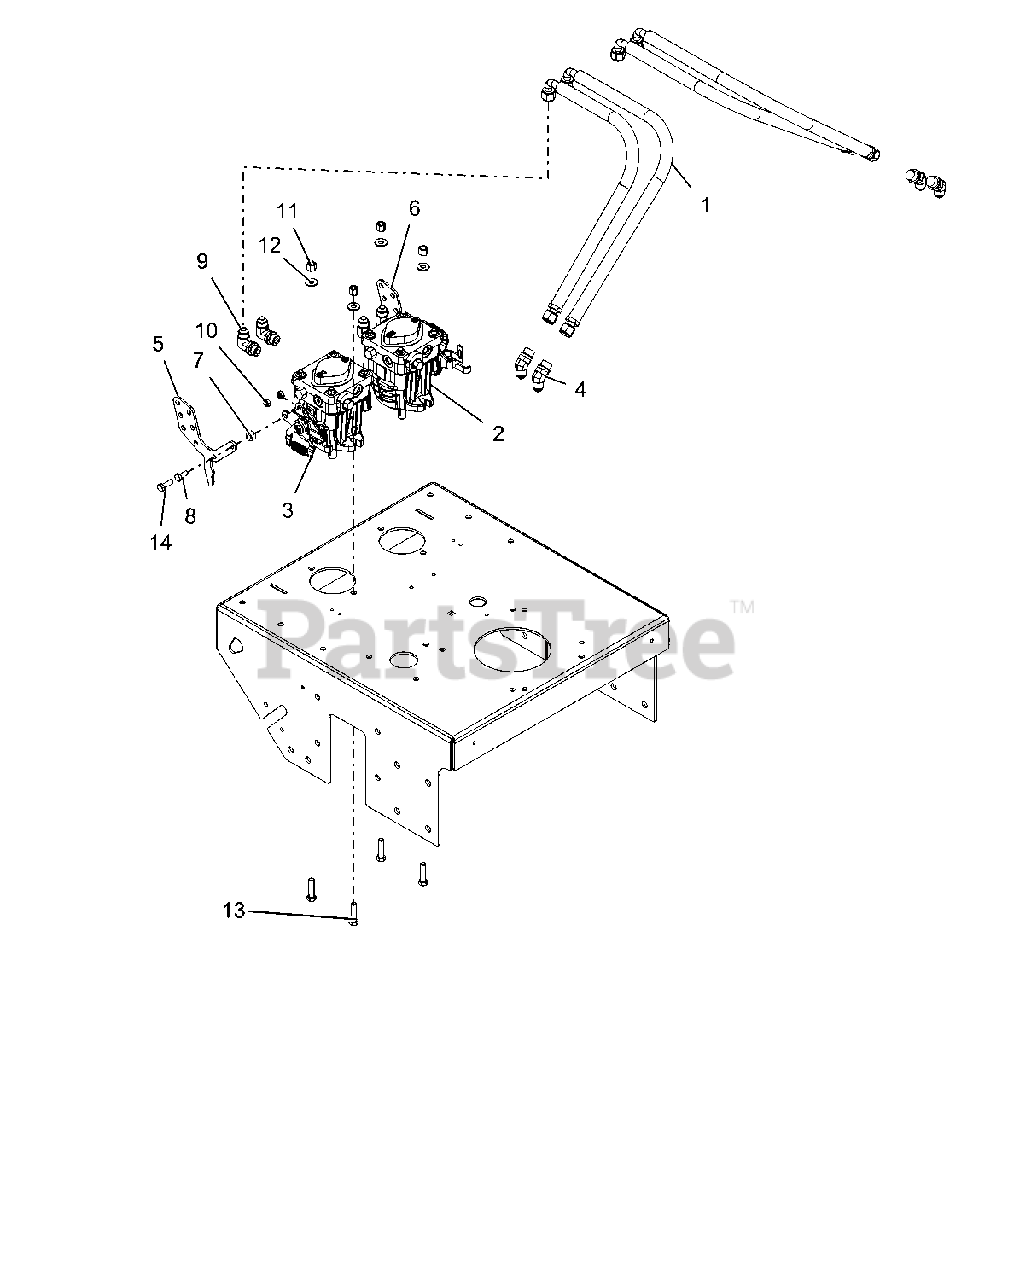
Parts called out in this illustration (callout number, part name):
1	HOSE, HYD 1/2 X 26 1/2 EZFLEX
2	PUMP, LH HYD PE (10CC)
3	PUMP, RH HYD PE (10CC)
4	45 DEGREE HIGH PRESSURE FITTING
5	BRKT, RH PUMP CONTROL WRS
6	BRKT, LH PUMP CONTROL WRS
7	BSHG, SLV REV
8	BLT-HEX .31-18X.75 GR5 YWZC
9	FTG, ADP JIC-ORB 6801-08-08
10	NUT-LK-CTR-JAM .31-18 YWZC
11	NUT-LK-NYL .38-16 YWZC
12	WSHR-FL-STL.38X.875X.083 YWZC
13	BLT-HEX .38-16X1.50 GR5 YWZC
14	BLT-HEX .31-18X1.00 GR5 YWZC
